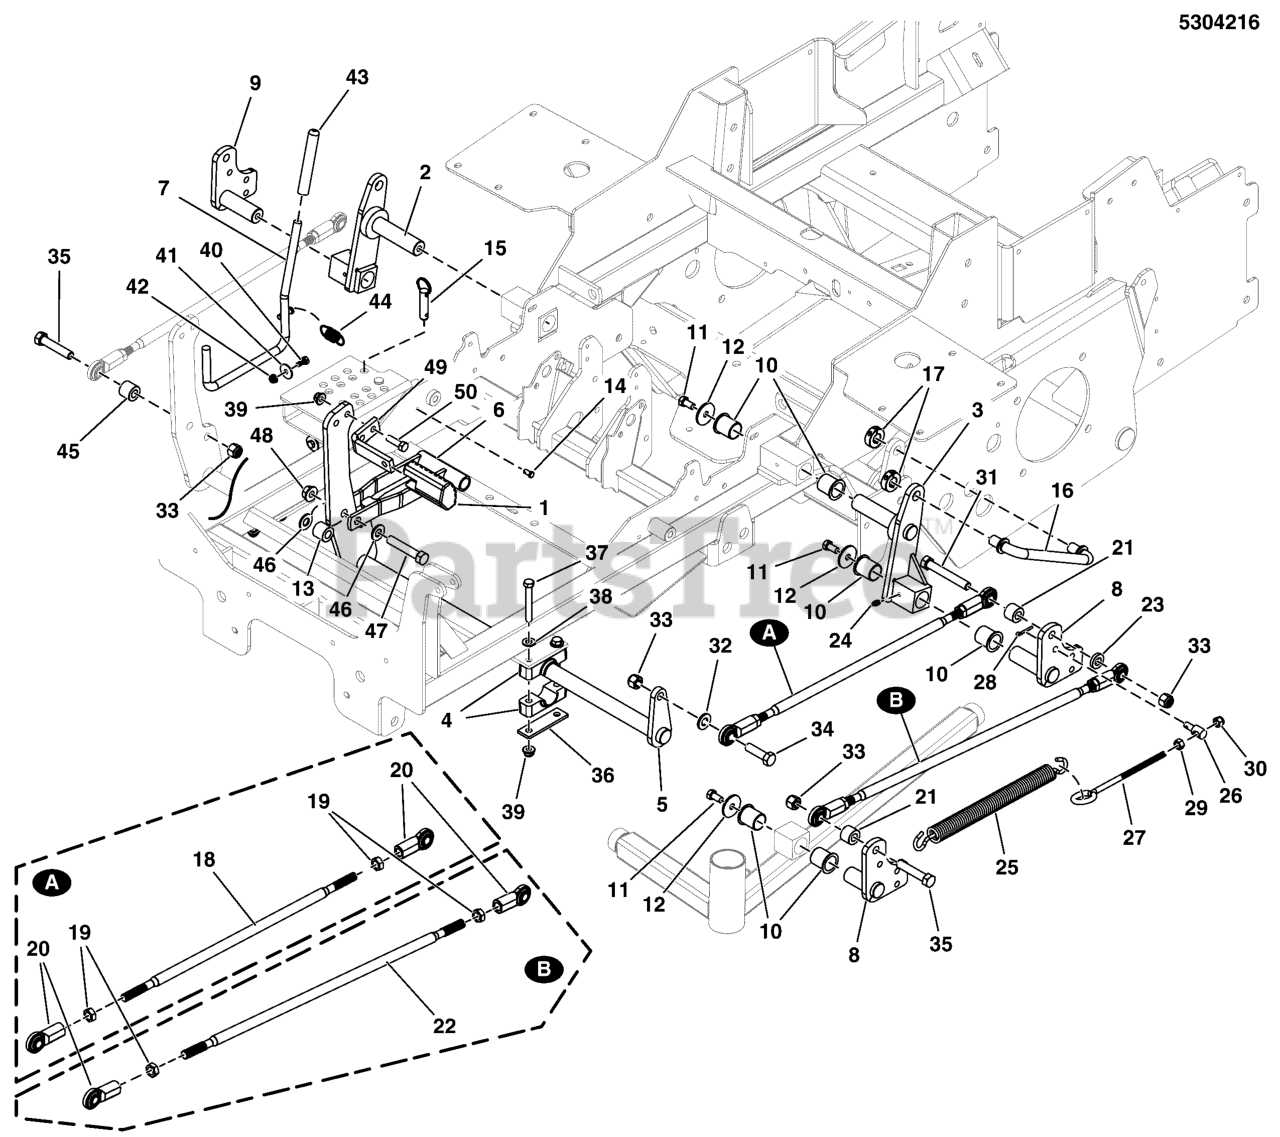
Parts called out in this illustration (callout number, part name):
1	PEDAL, Rubber
2	WELD, REAR LIFT - RH - BLK
3	WELD, REAR LIFT - LH - BLK
4	PIVOT BLOCK, PLASTIC
5	WELD, DECK LIFT SHAFT - RED
7	WELD, Rod, Deck Lift - BLK
8	WELD, DECK LIFT LEVER, LH - BLK
9	WELD, DECK LIFT LEVER, RH - BLK
10	BUSHING, 1.00 X 1.13 X 1.38, Plastic
11	BOLT, 3/8-16 X 3/4, PLT W/PATCH
12	WASHER, .390 X 1.50 X .109, YZ
13	SPACER, .52 X 1.00 X .63, YZ
14	PIN, CLEVIS, 1/4 X 1/2, PLATED
15	PIN, HITCH, 1/2 X 2.00 OAL, YP
16	ROD, SUSPENSION LINK, IS2600
17	COLLAR, 5/8" Split
18	ROD, DECK LIFT, 19.25, CZ
19	NUT, 1/2-20 Hex Jam
20	JOINT-BALL .500-20 THD .500ID, CLR ZINC
21	SPACER, .52 X 1.00 X .75, CZ
22	ROD, 1/2-20 X 24.50
23	SPACER, .52 X 1.00 X .22, PM, CZ
24	GREASE FITTING, 1/4-28 Straight
25	SPRING-EXT, 1.00 ODX13.25LGX.177WR, BLK
26	* ADJUSTER, DECK HANGER
27	EYE BOLT, 3/8-16 X 8, 3THRD, 1EYE, CZ
28	* PIN, COTTER, 1/8" X 3/4
29	NUT, 3/8-16 HEX, YZ
30	NUT, 3/8-16 HEX NYLON LOCK
31	BOLT, 1/2-13 X 3-1/4, HEX HD, GD5, CZ (SV)
32	WASHER, 1/2" GD9 YZ
33	NUT, 1/2-13 HEX NYLON LOCK
34	BOLT, 1/2-13 X 1-3/4 GD5 CZ
35	BOLT, 1/2-13 X 2-1/2" GD5 CZ
36	PLATE, PIVOT BLOCK SUPPORT - BLK
37	BOLT, 3/8-16 X 2-3/4" GD5 CZ
38	WASHER, 3/8 SAE
39	NUT, 3/8 - 16 HEX NYLOCK FLANGE
40	HHCS, 1/4-20 X 0.625, GR5, ZINC/CLEAR
41	WASHER, 1/4" Fender
42	NUT, 1/4-20 Hex Nylock Flange
43	GRIP, FOAM, .475 X 4.35 X .095
44	SPRING-EXT, .740 ODX2.025LGX.072WR, BLK
45	SPACER, .52 X 1.00 X .88, PM, CZ
46	WASHER, 1/2 SAE
47	BOLT, 1/2-13 X 2-3/4 GD5 CZ
48	NUT, Hex Flange, Nylock, 1/2-13
49	PEDAL, FOOT - BLK
50	BOLT, 3/8-16 X 1-1/4" GD5 CZ
